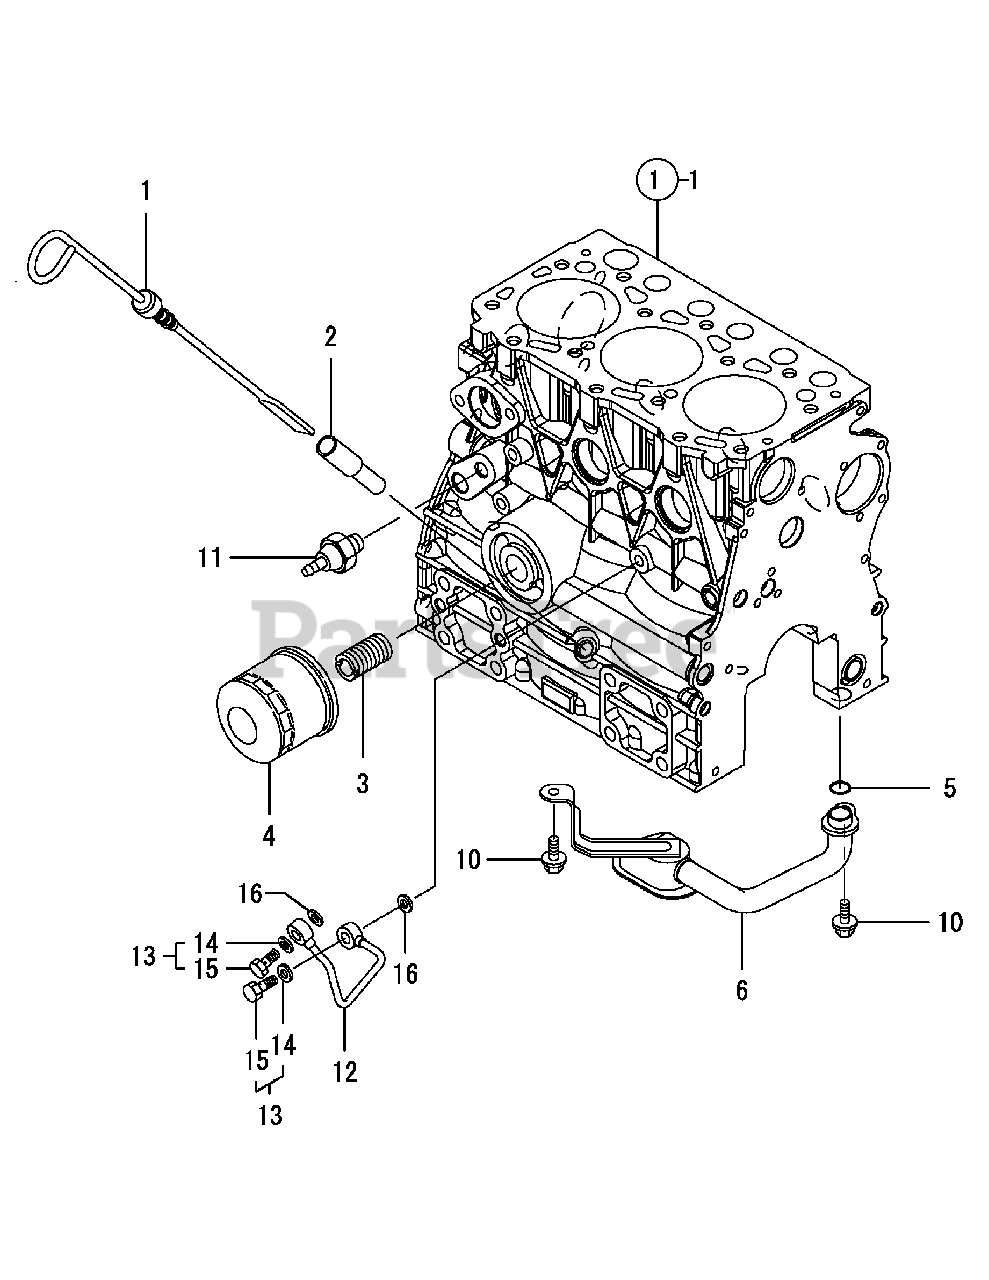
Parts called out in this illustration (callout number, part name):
1	DIPSTICK, LUB.OIL
2	GUIDE, DIPSTICK
4	FILTER ASSY, LUB.OIL
6	PIPE ASSY,LUB.OIL
10	BOLT 6X 10 PLATED
11	SWITCH, (0.5KG) L.O.
12	PIPE ASSY, HYDRAULIC
13	BOLT ASSY, JOINT
14	SEAL WASHER 8S
16	SEAL WASHER 8S
